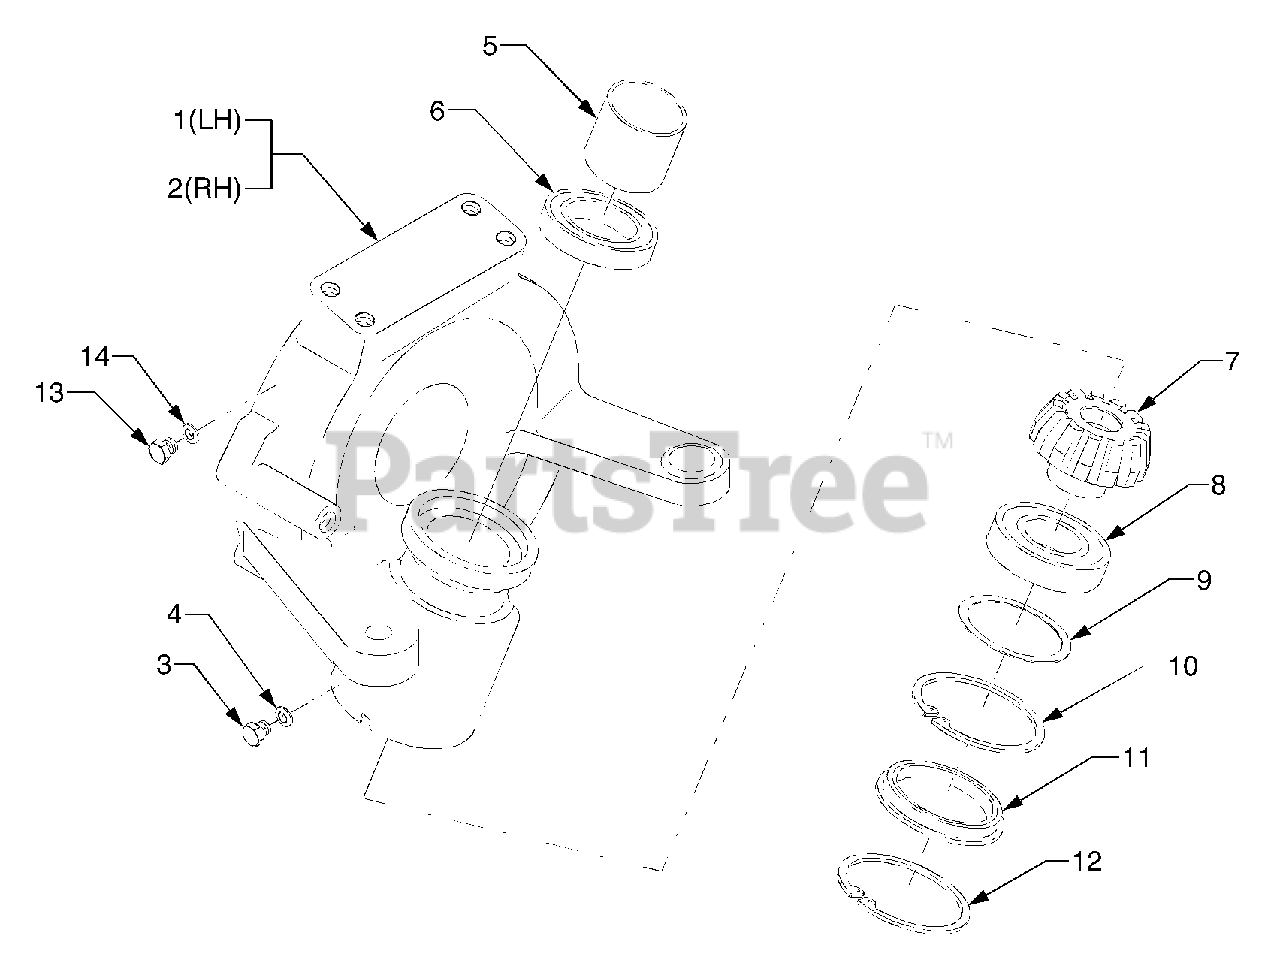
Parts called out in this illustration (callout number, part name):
1	Case, Front Axle (LH)
2	Case, Front Axle (RH)
6	Bearing, Thrust
7	Gear, 11 Bevel
8	Bearing, Ball
